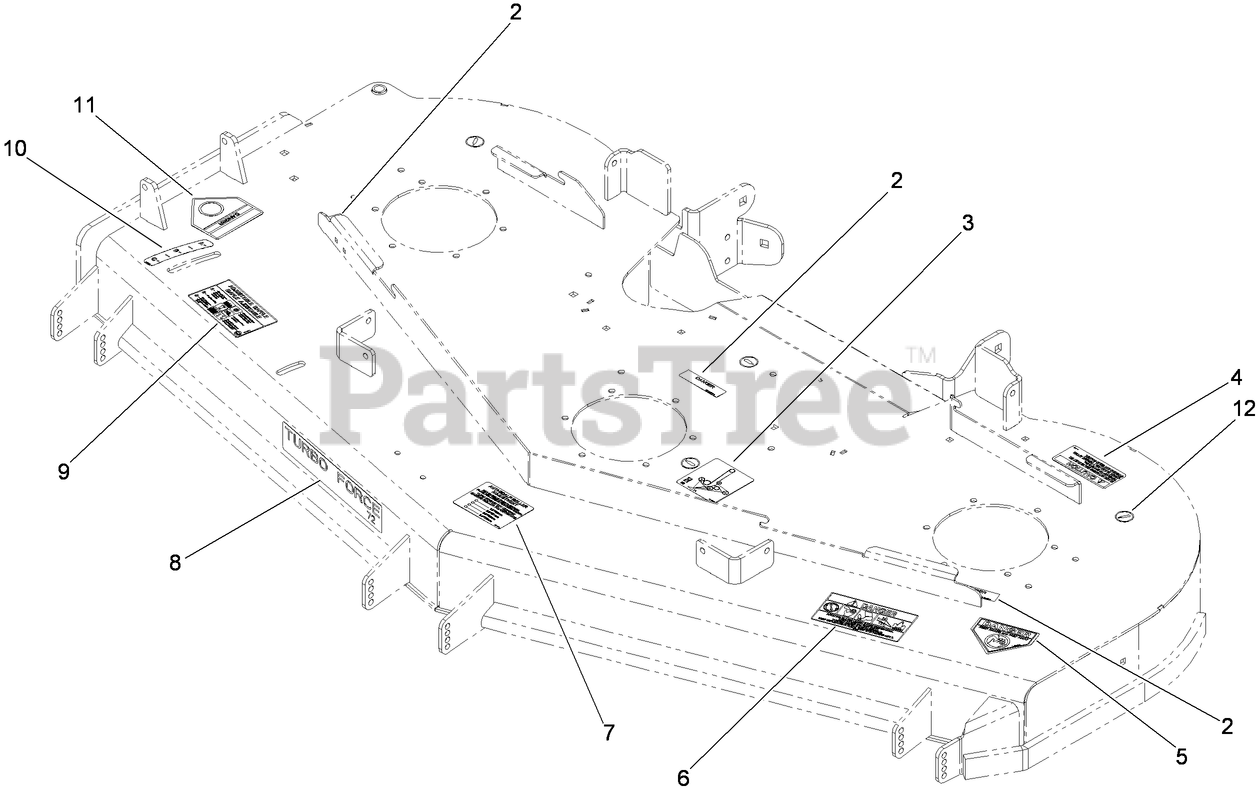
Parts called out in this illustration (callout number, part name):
2	DECAL-COVER, MISSING
3	DECAL-ROUTING, DECK BELT
4	DECAL-TORQUE
5	DECAL-DANGER
6	DECAL-DANGER, THROWN OBJECT
7	DECAL-SCALP, ANTI
9	DECAL-ADJUSTMENT, BAFFLE
10	DECAL-SETTING, BAFFLE
11	DECAL-DANGER
12	DECAL-GREASE
